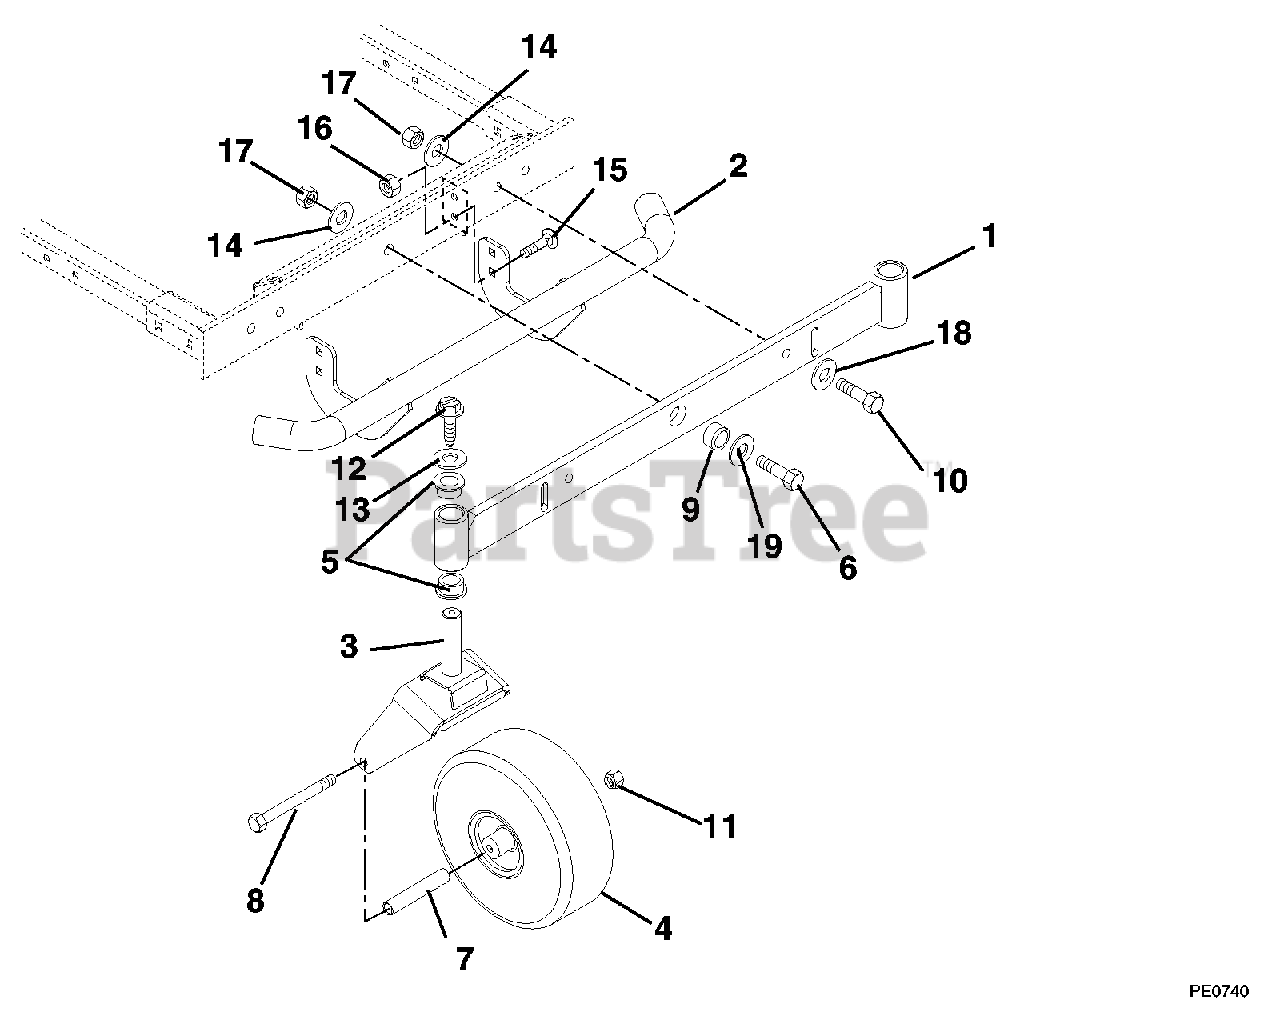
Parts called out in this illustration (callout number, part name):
1	Weldment, Front Axle
2	Bumper, Zoom
3	Fork, Caster
4	Assembly, Tire 4 x 11- 2 Ply
5	Bushing, Flange 1.00 x 1.25 x 1.50 x 1.50
6	Bolt, Hex .62-11 x 2.50 Grade 5
7	Bushing, Caster Fork
8	Bolt, Hex .50-13 x 6.50 Grade 5
9	Bushing, Axle Pivot
10	Bolt, Shoulder .75 .625-11 x 2.25 Socket Head Cap Skrew
11	Nut, Locking Top Flange .50-13
12	Screw, Tapping .38-16 x 1.25 Hex Washer Head
13	Washer, Flat Steel .38 x 1.50 x .125
14	Washer, Flat .64 x 1.81 x .25
15	Bolt, Round Head Square Neck .38-16 x 1.00 Grade 5
16	Nut, Locking Top Flange .38-16
17	Nut, Locking Nylon .625-11
18	Washer, Flat Steel .812 x 1.50 x .135
19	Washer, Flat Steel .688 x 1.75 x .134
